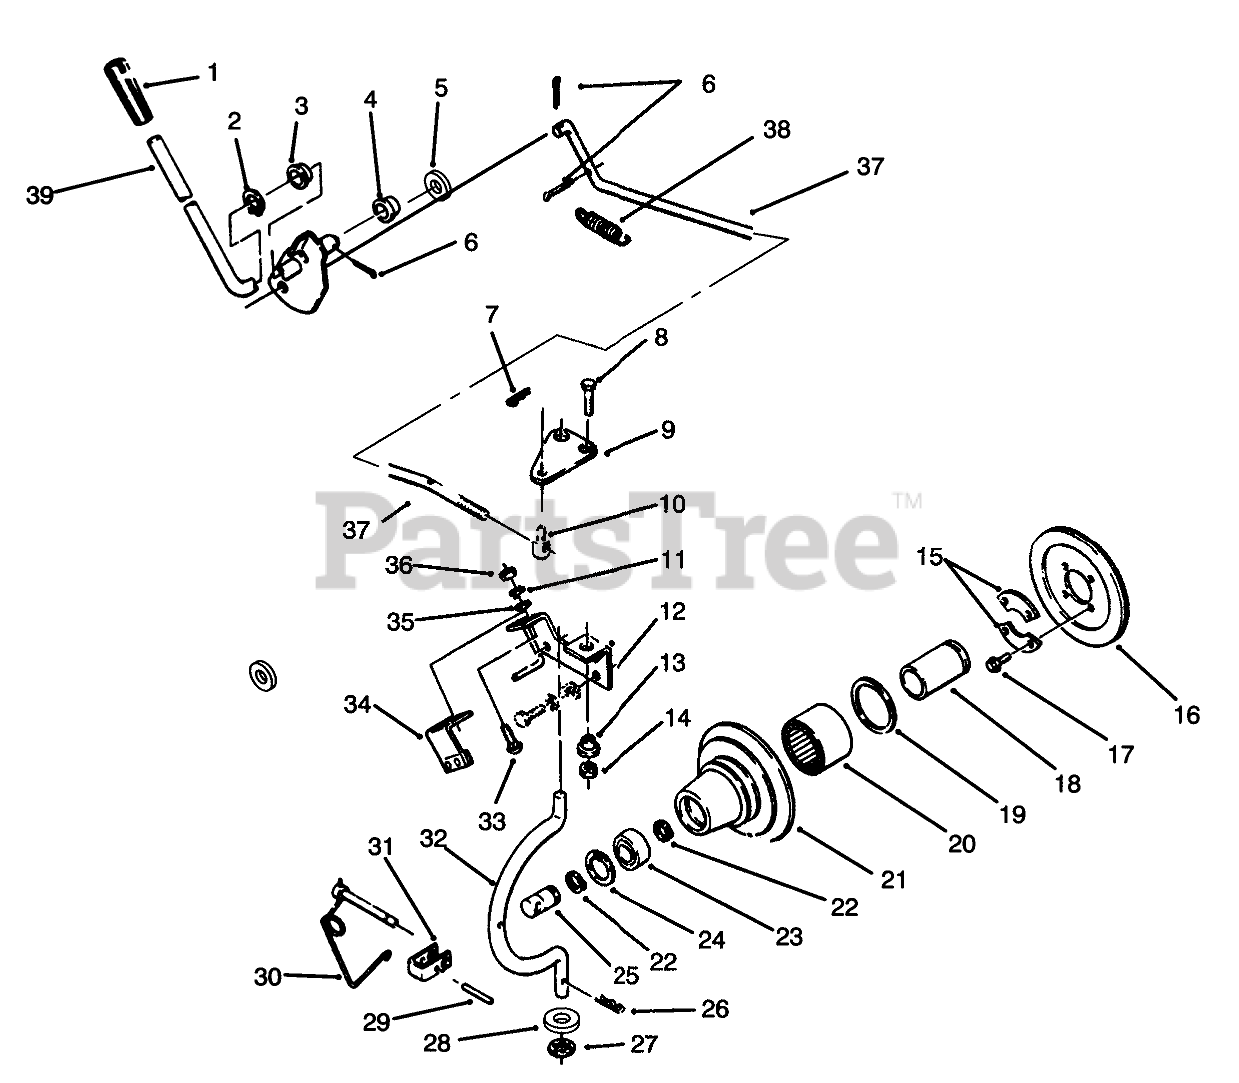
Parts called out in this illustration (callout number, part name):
1	GRIP
2	RING-EXT GRIP
3	BUSHING-NYLINER
4	NYLINER BUSHING
5	SHIM-WASHER
6	PIN-COTTER
7	PIN-HAIR
8	SCREW-HH
9	PLATE
10	TRUNNION
11	WASHER-LOCK
12	Bracket-Engine
13	SPACER-LIFT LINK
14	NUT-LOCK, NI
15	RETAINER
16	Facing-Clutch
17	SCREW-HEX HD CAP
18	RACE-BEARING
19	SEAL-OIL
20	Seal
21	Housing-Clutch
22	Ring-Snap
23	BEARING-BALL
24	RING-RETAINING
25	SHAFT-PTO
26	PIN-COTTER, HAIR
27	RING-REINFORCED CIRC
28	WASHER-FLAT
30	LOCKING PIN ASM
31	CLEVIS
32	ROD-HOUSING
33	SCREW-CARR
34	ASM-Bracket
35	WASHER-FLAT
36	NUT-JAM
37	ROD-PTO CLUTCH
38	SPRING
39	ASSY PTO CLUTCH LEVE
